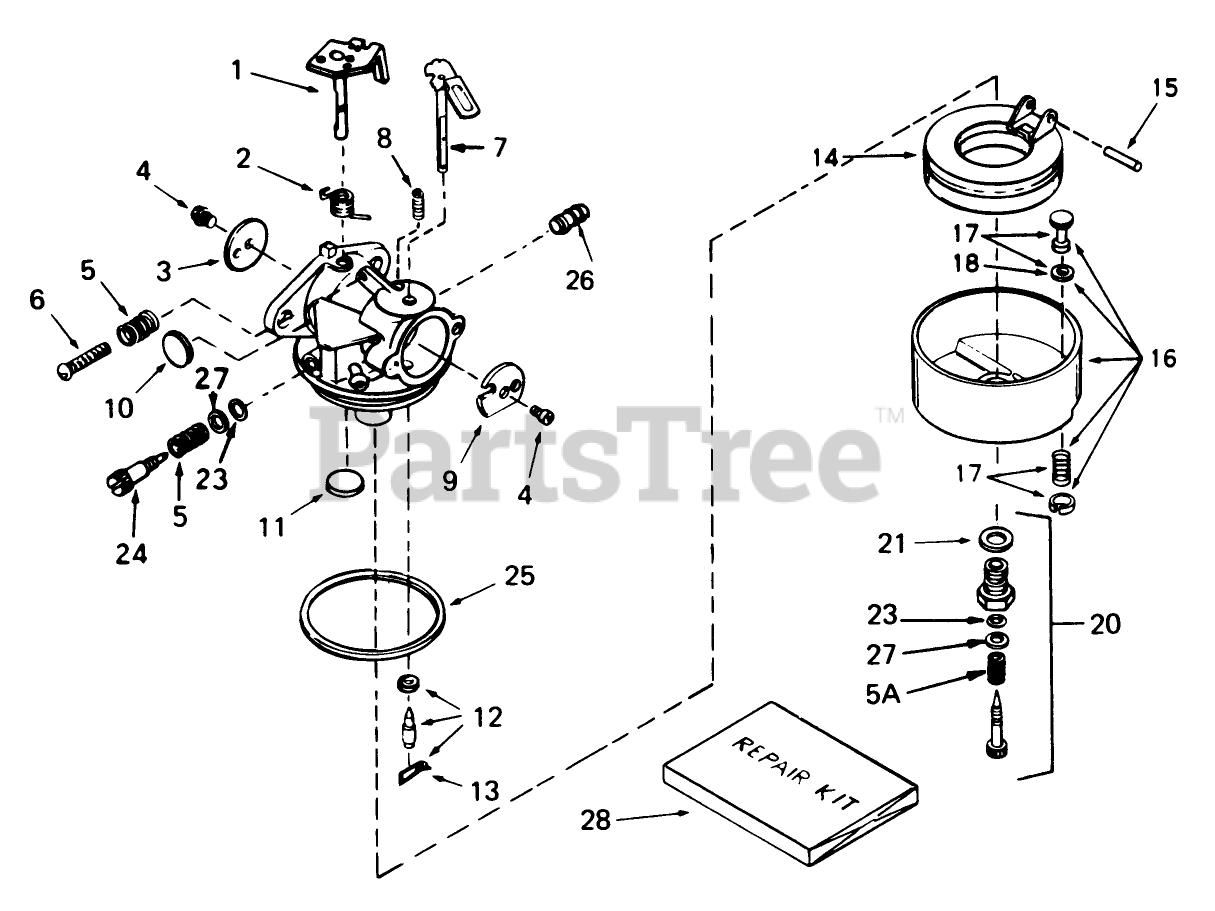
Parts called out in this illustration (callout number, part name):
1	Throttle Shaft and Lever ASM
2	Spring-Return, Throttle
3	Shutter-Throttle
4	Screw-Shutter
5	Spring-Tension
5A	Spring
6	Screw-Throttle Crack Screw / Idle Speed
7	Choke Shaft and Lever ASM
8	Spring-Positioning, Choke
9	Shutter-Choke
10	Plug-Welch, Idle Mixture Well
11	Plug-Welch, Atmospheric Vent
12	Inlet Needle, Seat Clip Assy. (Incl. No. 13)
13	Clip-Spring
14	Float
15	Shaft-Float
16	Float Bowl Asm. (Incl. Ref. # 32, 33)
17	Bowl Drain ASM
18	Gasket-Plunger, Drain
20	Adjustment Screw Assy.,Main (Incl. Ref. #5A,21,23 30)
21	Washer-Bowl Nut
23	ORing
24	Screw-Idle Mix
25	O Ring-Bowl, Float
26	Fitting-Fuel
27	Washer
28	Kit-Repair
